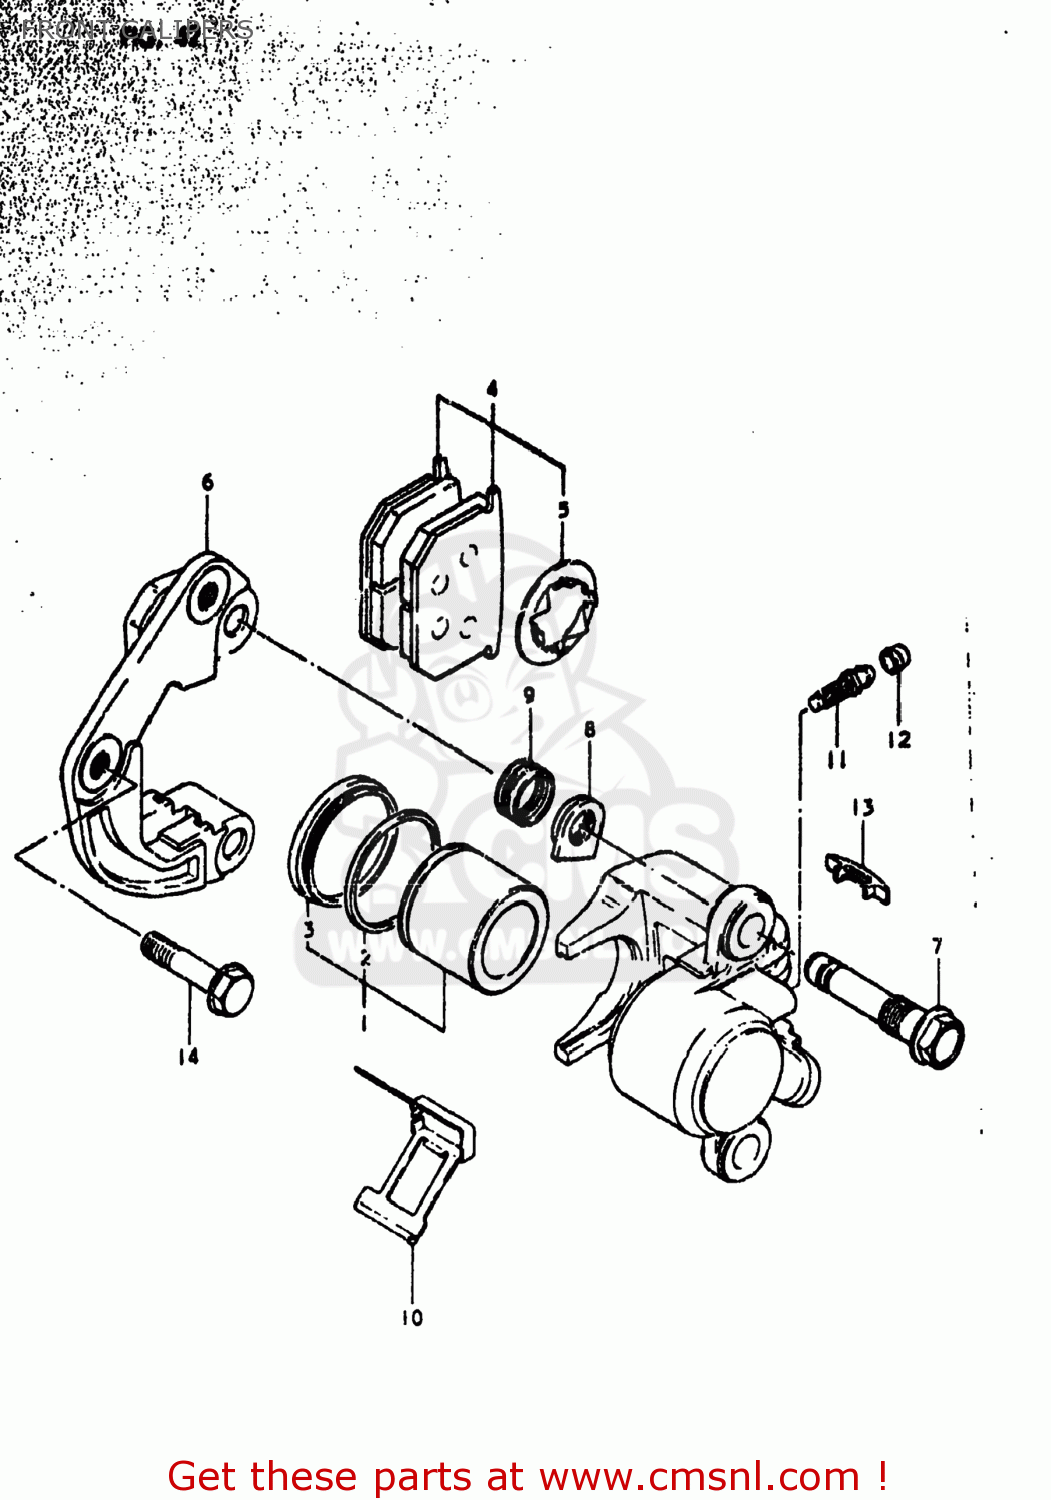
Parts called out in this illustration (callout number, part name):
1	PISTON SET
2	SEAL,PISTON
3	BOOT,PISTON
4	PAD & SHIM SET (MCA)
5	SHIM,PAD
6	BRACKET
7	AXLE,CALIPER
8	NUT,CALIPER AXLE
9	BOOT
10	SPRING
11	BREATHER
12	CAP,BLEEDER PL
13	COVER,INDICATOR
14	BOLT(10X37)
